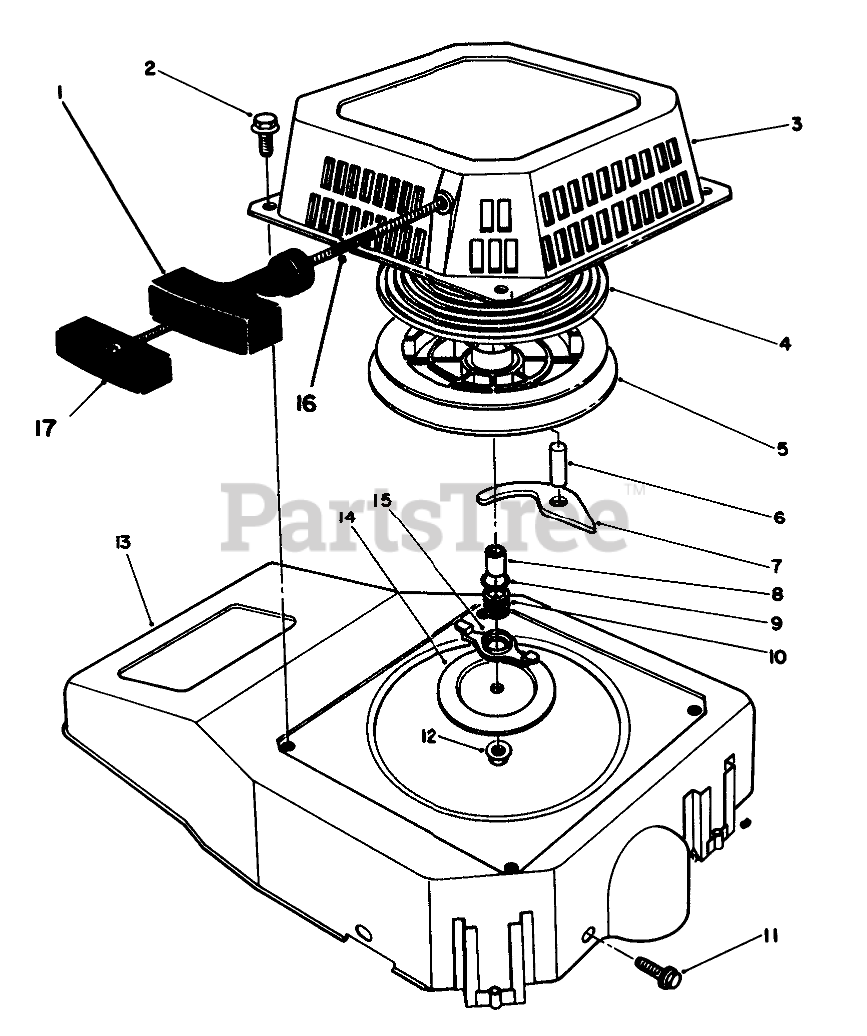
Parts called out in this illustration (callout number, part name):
1	HANDLE
2	SCREW-HHF
3	Case-Recoil
4	SPRING
8	Spacer
9	WASHER
10	Spring-Friction
13	SHROUD
14	PLATE
15	Guide-Paw
16	ROPE-STARTER
17	RETAINER HANDLE
